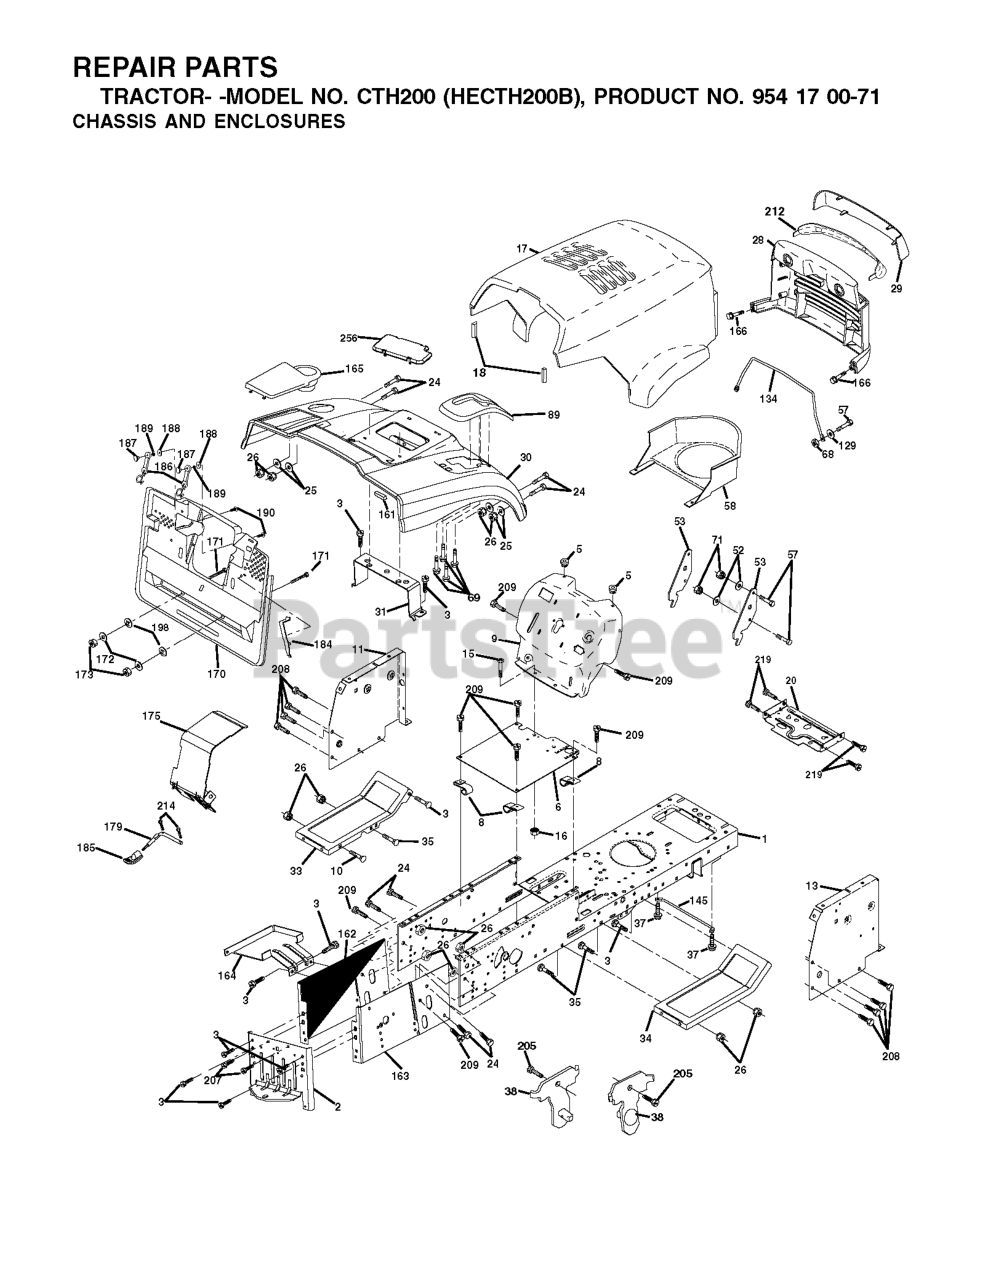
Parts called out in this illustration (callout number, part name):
2	DRAWBAR
3	SCREW 3/8-16X3/4
5	BUMPER.RUBBER.HOOD
6	SADDLE FLAT
8	CLIP,INSULATOR
10	BOLT D
11	PANEL.DASH.LH.LTX
13	PANEL ASM, DASH RH
15	Screw, Machine, Truss Head 5/16-18 UNC x 3/4
16	NUT
17	HOOD
18	BUMPER HOOD T
20	PLATE MTG.BATTERY/FUEL TANK
25	WASHER
26	NUT
28	GRILL
29	LENS
31	BRACKET SUPPORT FENDER
33	FOOTREST PNT LH
34	FOOTREST PNT RH
37	Screw 5/16-18 x 1/2 Hex, Self Tapping 5/16-18 x 1/2
38	BRACKET ASM PIVOT MOWER REAR
53	BRACKET PNT PICK OFF LT/PL
57	BOLT
58	DUCT, INTAKE AIR
68	NUT
69	SCREW.HI-LO.CONSOLE
71	NUT.CROWNLOCK.1/4
89	COVER.BATTERY.CRD.GREY
134	ROD SUPPORT HOOD LT/PL HUS.
145	ROD PIVOT CHASSIS/HOOD
161	EXTRUSION BUMPER (3 2) (2 2)
162	BRACKET
163	BRACKET EXTEN CHASSIS RH CRD
164	SUPPORT
165	RP.COVER.BATTERY.CRD.GREY
166	SCREW
172	WASHER
173	NUT
184	BRACKET.ACTUATOR.BAGGER.SRD
186	LATCH ASSY
187	WELDNUT
189	LOCKWASHER #10
190	SCREW
207	SCREW, 5/16-18 X 1/2
208	SCREW 3/8-16X1/2
209	SCREW, 3/8-16X3/4
212	INSERT LENS REFLECTOR
214	RETAINER M
215	SCREW 5/16-18X1/2"
219	SCREW
